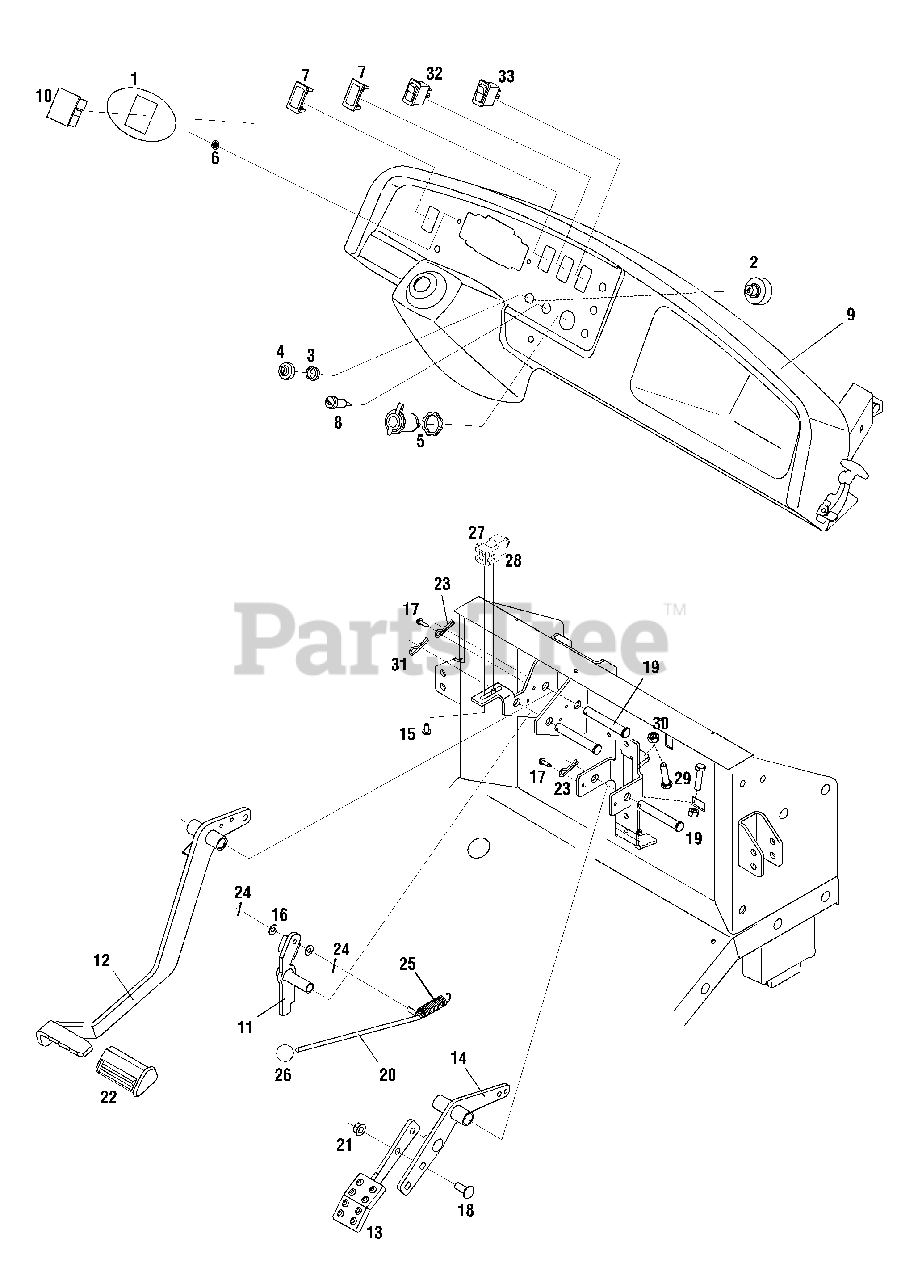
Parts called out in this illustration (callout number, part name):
1	Instrument Dash Cover
2	Key Switch
3	Nut, Ignition Switch, 5/8-32
4	Cap, Ignition Switch
5	Power Receptacle, 12V
6	Nut, Retainer, 1/8
7	Switch Plug Panel
8	Horn Switch
9	Dash Panel
10	Hour Indicator Meter
11	Lever, Parking Brake
14	Pedal Arm Assembly, Throttle
15	Screw, Hi-Lo, 1/4-20 x .5
16	Washer, Flat .25 x .630 x .0515
17	Screw, Self-tapping, #10-32 x.625
18	Bolt, Carriage, 3/8-16 x 1.0
19	Pin, Clevis.50 x 3.25
20	Rod, Brake Lock
21	Nut, Flange Lock, 3/8-16
22	Pad, Brake Pedal
23	Pin, Cotter,.125 x 1.75
24	Pin, Cotter, 1/16
25	Spring, Extension, .637 x 2.972
26	Knob, Ball
27	Cover, Protective
28	Snap Mount Switch, Interlock
29	Hex Screw, 5/16-18 x 1.25
30	Hex Nut, 5/16-18
31	Cotter Pin
32	Bed Lift Switch
33	Power Receptacle Switch
